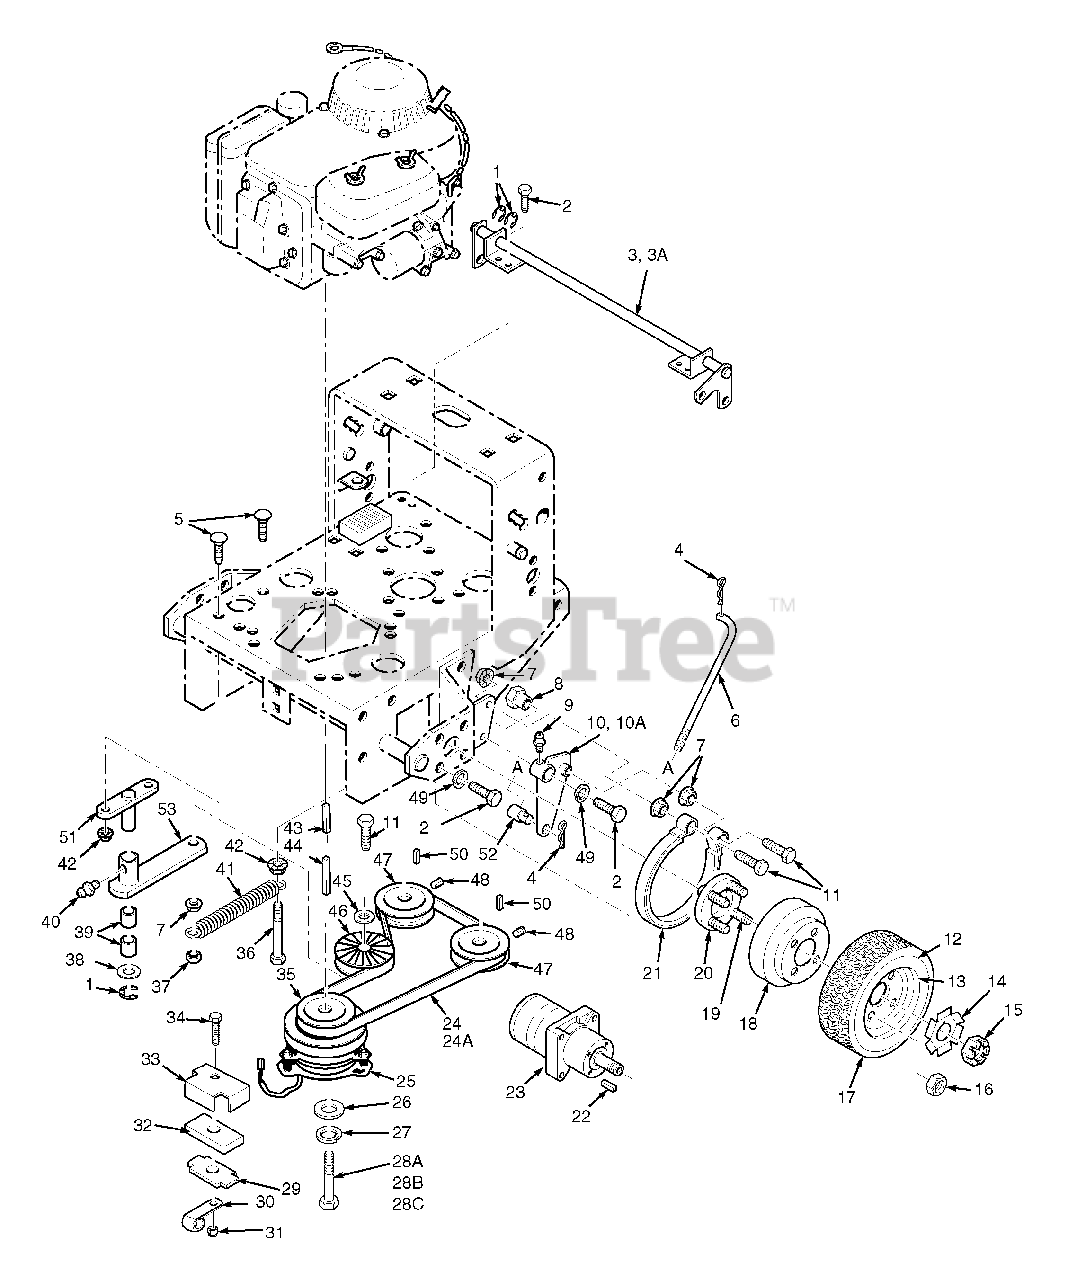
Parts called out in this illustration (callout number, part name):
1	Retaining Ring, 3/4 Ext. "E"
2	Bolt, 3/8-16 x 1" Hex Head
3	Brake Shaft Assy. Wlmt.Small
3A	Brake Shaft Assy. Wlmt.Large
4	Hair Pin Cotter, .094 x 1.62
5	Carrage Bolt, 5/16-18 x .75"
6	Rod, Brake Lower
7	Nut, 3/8-16 Serr. Flange
8	Bushing, Brake
9	Grease Fitting
10	Brake Actuator Wlmt., LH
10A	Brake Actuator Wlmt., RH
11	Bolt, 3/8-16 x 2-1/4"
12	Tire, 16 x 6.50, 4 ply
13	Rim Assy
14	Lock Washer, Wheel Motor
15	Hex Castle Nut, 3/4-28 UNEF
16	Nut, Lug
17	Wheel Assy.,
18	Brake Drum
19	1/2-20 Serrated Bolt
20	Hub, Wheel
21	Brake Band, 7.5"
22	Key, 3/16 X .75 Woodruff
23	Wheel Motor
24	Belt, Pump Drive (Sm Frame)
24A	Belt, Pump Drive (Lg Frame)
25	Electric Clutch
26	Flat Washer .469 x 1.75 x .25
27	Lock Washer, 7/16
28A	Hex Head Bolt, M10-1.5 x 65
29	Plate, Backing
31	Nut, 5/16-18 Elastic Stop
32	Rubber Pad, Clutch Stop
33	Retainer, Clutch Stop
34	Hex Head Bolt, 5/16-18 x 1.75"
35	Pulley, Pump Drive Engine
36	Hex Head Bolt, 5/16-18 x 2.75"
37	Nut, 3/8-16 Center Lock
38	Washer, 3/4-.766 x 1.2 x .06
38	Washer, 3/4-.766 x 1.2 x .035
39	Bushing, 3/4 Sintered
40	Grease Fitting, Str. 1/4-28
41	Spring, Pump Belt Idlerx
42	Nut, 5/16-18 Serr. Flange
43	Key, 1/4x1/4x2.75" Clutch Mtg.
44	Key, 1/4x1/4x1.25" Pulley Mtg.
45	Flat Washer, 3/8
46	Pulley, Idler Pump Drive
47	Pulley, Pump Shaft
48	Setscrew, 5/16-18 x 3/8"
49	Lockwasher, 3/8
50	Key, 5.0 x 5.0 x 25mm
51	Pivot, Idler Arm
52	Swivel Joint
53	Arm, Idler
